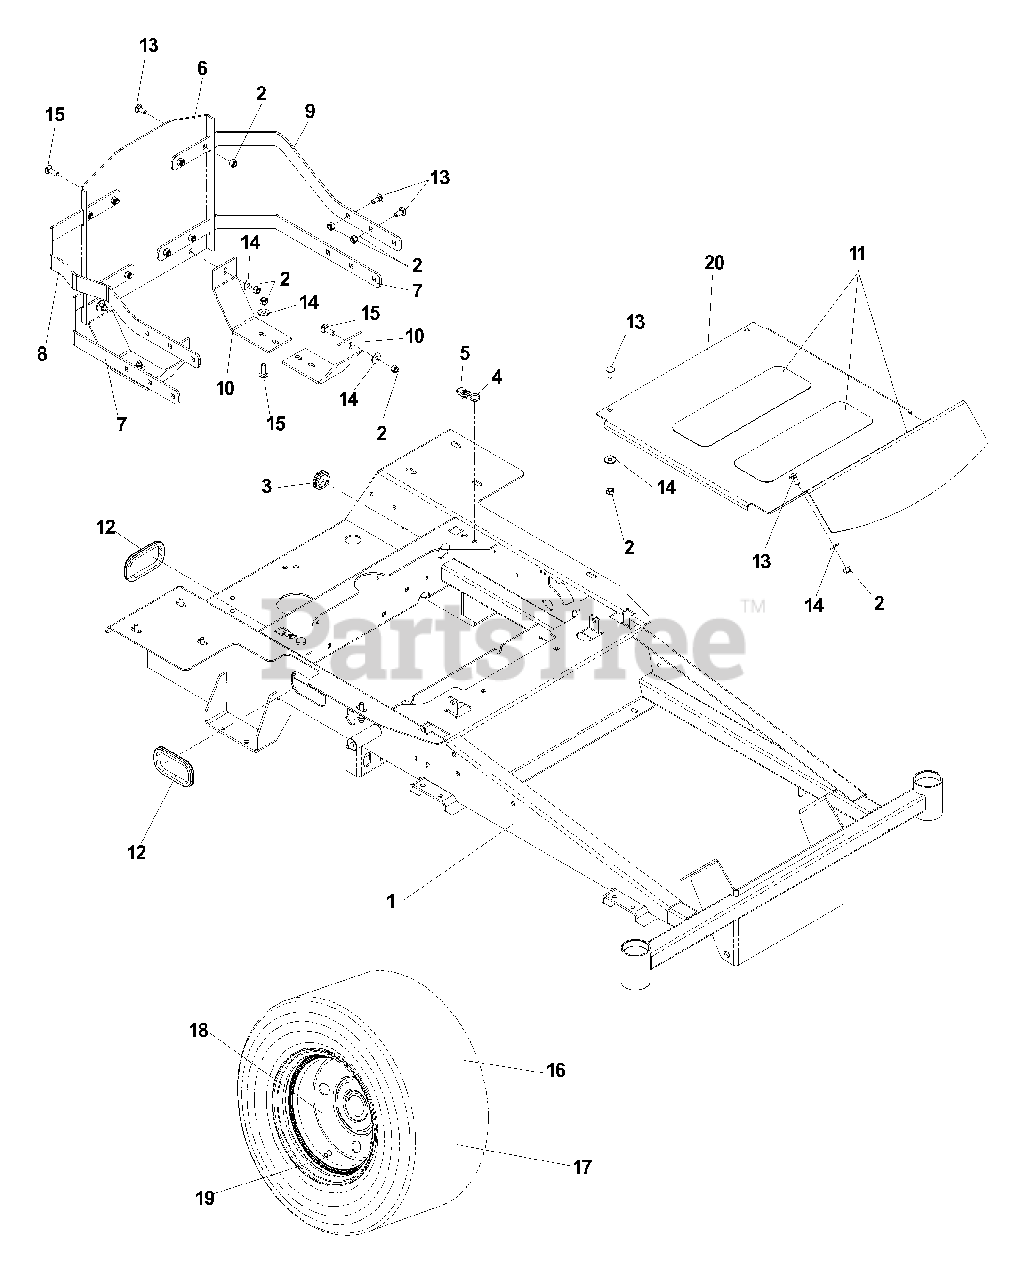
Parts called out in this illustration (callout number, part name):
1	MAIN FRAME W/DECALS
1	MAIN FRAME W/DECALS,
2	NUT, 5/16-18, NYLOC
3	RUBBER GROMMET
4	GROMMET, BUMPER
5	NUT, 5/16-18, RETAINER-U TYPE
6	ENGINE GUARD
7	LOWER GUARD
8	UPPER RIGHT HAND GUARD
9	UPPER LEFT HAND GUARD
10	SKID PLATE
11	PAD, ABRASIVE
13	RHSNB, 5/16-18 X 3/4, GR5
14	WASHER, 5/16
15	RHSNB, 5/16-18 X 1, GR5
16	TIRE & RIM
17	TIRE
18	RIM
19	VALVE STEM
